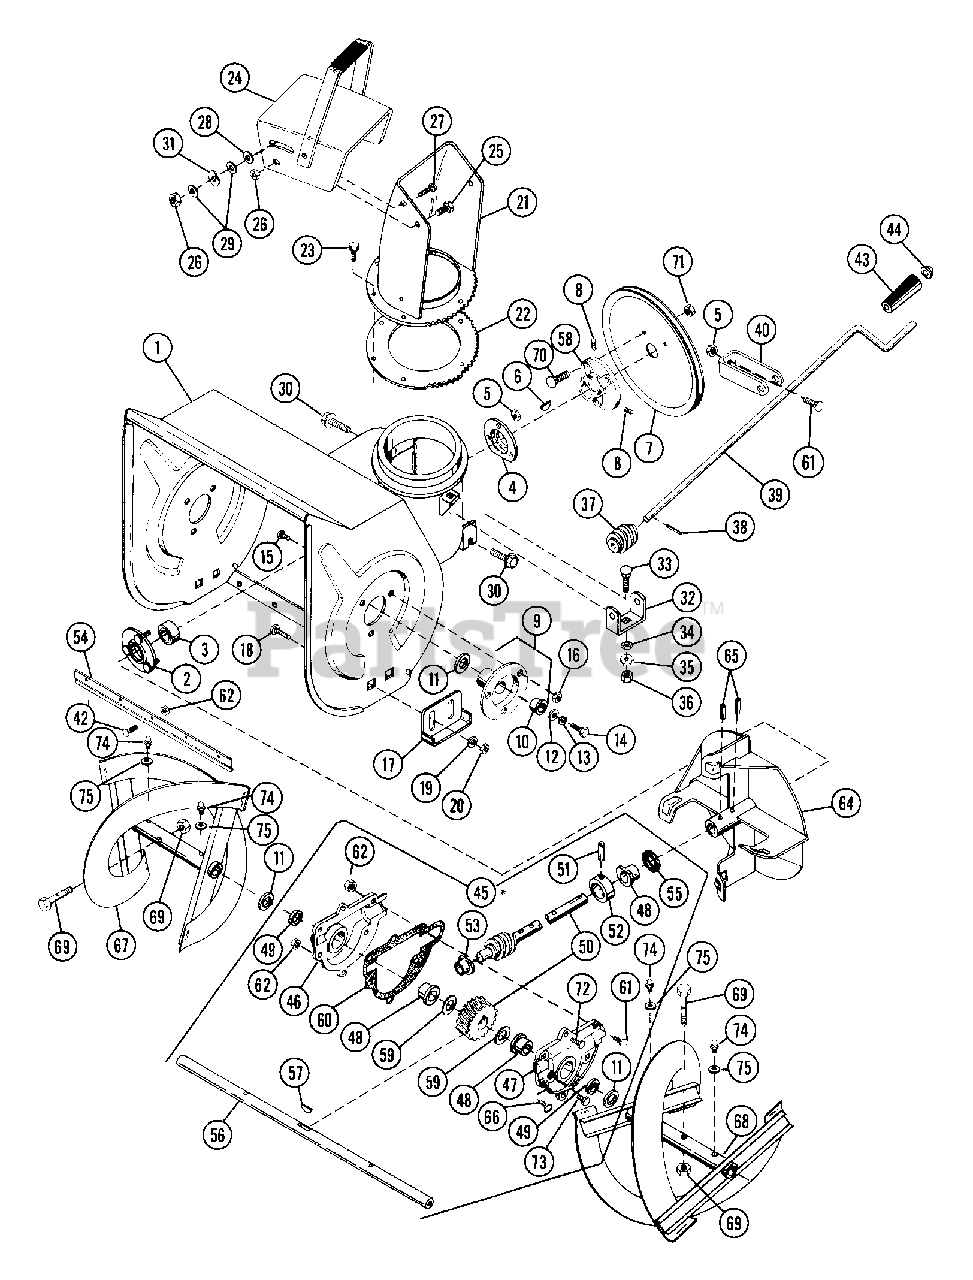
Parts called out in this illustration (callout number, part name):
1	20 IN BLOWER HOUSING WITH DECA
2	BEARING FLANGE
3	BRG-BALL .750X1.750X.50
4	BEARING FLANGE
5	NUT-LK-CTR .250-20 PL
6	KEY-WDRF .188X.875X.375 SAE11
7	PLY-V 7.0 X 1.25 3BLT
8	SCR-SET .32-18X.38 SKHCUPNL OH
9	BEARING FLANGE ASSEMBLY
10	BSHG-FLG .750X1.000X.625X1.250
11	WSHR-FL-STL.812X1.500X.139
12	WSHR-FL-STL .344X1.375X.075 PL
13	WSHR-LK .312X.097 PL HVY
14	BLT-HEX .31-18X.63 PL GR 2
15	BLT-SERNK SL .25-20X.50 PL
16	NUT-LK-FLG .250-20 PL
17	RUNNER
18	BLT-RDHDSQNK .38-16X.75 SHT PL
19	WSHR-FL-STL .38X.875X.083 PL
20	NUT-LK-CTR .375-16 GR A PL
21	CHUTE - DISCHARGE
22	GEAR - LOWER COLLAR
23	SCR-TAP 8-32X.38 SL HWH PL 23
24	DEFLECTOR SERVICE ASSEMBLY
25	BLT-HEX .31-18X.50 PL GR2
26	NUT-LK .312-18 GR A PL
27	BLT-RDHDSQNK .31-18X.75 SHT PL
28	WSHR-PLASTIC .390X.875X.062
29	WSHR-FL-STL .323X.625X.062 PL
30	BLT-SERHFWH .31-18X.50 PL
31	WAVE WASHER .390X.655X.110
32	WORM CLEVIS
33	BLT-RDHDSQNK .31-18X.75 GR5 PL
34	WSHR-LK .313X.062
35	WSHR-LK-EXT .375X.035 PL
36	NUT-HEX .312-18
37	WORM GEAR
38	PIN-ROLL .125X.75
39	CHUTE CONTROL CRANK
40	BRACKET WITH DECAL
42	BLT-RDHDSQNK .25-20X.50 SHT PL
44	CAP, 3/8 ROD YWZC
45	GEAR CASE - 20" - ALUMINUM
46	R H GEAR CASE HALF
47	L H GEAR CASE HALF
48	BSHG-FLG .750X1.000X.750X1.250
49	SEAL .750X1.000X.125
50	SHAFT AND WORM GEAR ASSEMBLY
51	PIN-GRV .188X1.25 TP A
52	THRUST COLLAR
53	BSHG-FLG .500X.750X.750X1.000
54	SCRAPER BLADE
55	O-RING .250X.943X.103
56	SHAFT, RAKE - 20"
57	KEY-WDRF .188X.625X.25 SAE 61
58	HUB
59	WSHR-HDND-THRST .755X1.40X.062
61	BLT-RDHDSQNK .25-20X1.25 GR5PL
62	NUT-LK-FLG .250-20 PL
64	IMPELLER - 10"
65	PIN-ROLL .250X1.25
66	BLT-RDHDSQNK .25-20X.88 PL
67	RAKE, RIGHT-20(.75ID X10.88OD)
68	RAKE, LEFT-20"(.75OD X10.88OD)
69	SHEAR BOLT WITH NUT
70	BLT-SERRDHD SL .31-18X.75 YZ
71	NUT-FLG. .312-18 PL
72	SCR-TAP 10-24X.75 HWH PL TR
73	BLT-SCRHFWH .38-16X.50 PL
74	SPIN DRIVE ZERK FITTING
75	WSHR-FL-STL .265X.500X.087 PL
